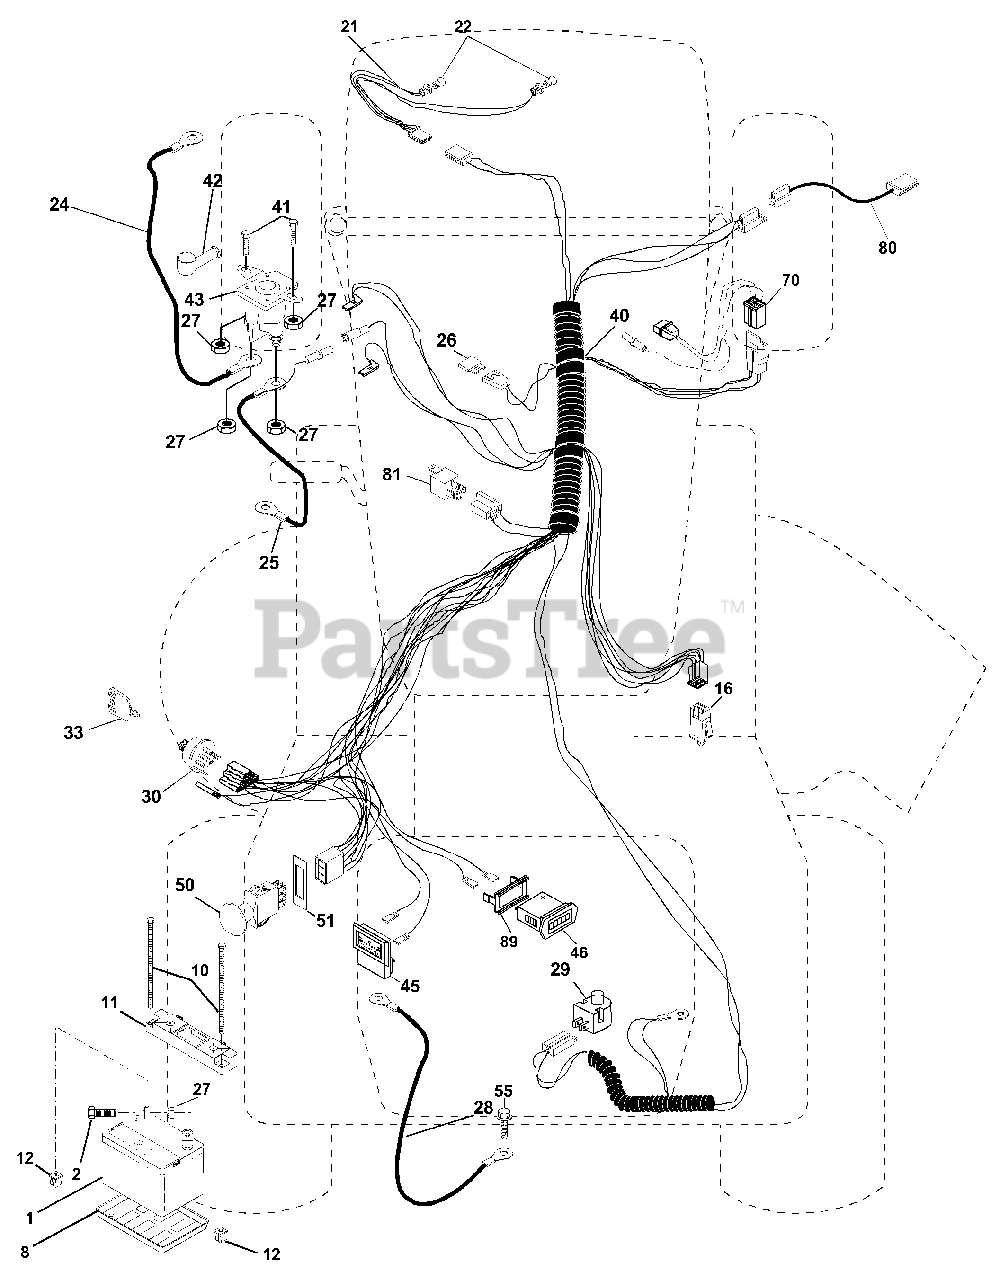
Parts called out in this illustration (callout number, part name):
1	Battery 12 Volt 28 AMP
2	Bolt Hex Hd 1/4-20 UNC X 3/4
8	Tray, Battery
10	Bolt, BTR FRT 1/4-20 x 7.5
11	Hold Down Battery, Front
12	Nut, Push, Nylon
16	Switch Interlock Push-In
21	Harness Asm Light W/4152j
22	Bulb Light #1156
24	Cable Battery 6 Ga 11" red
25	Cable Batterywire
26	Fuse 15 AMP
27	Nut Keps Hex 1/4-20 Unc
28	Cable Ground
29	Switch Plunger Normal OP Olive
30	Switch Ign 4 pos w/lights
33	Key Ign
40	Harness Ign.
41	Bolt Blk Fin Hex 1/4 - 20 x 1/2
42	Cover Terminal Red
43	Solenoid
45	Ammeter Rectangular
46	Hourmeter Snap-In
50	Switch, PTO 3PDT Black Delta
51	Ring Retainer PTO
55	Screw Thdrol 5/16-18 x 1/2
70	Harness, Eng.
80	Harness, Clutch EVX
81	Relay Asm
89	Bracket Snap-In
